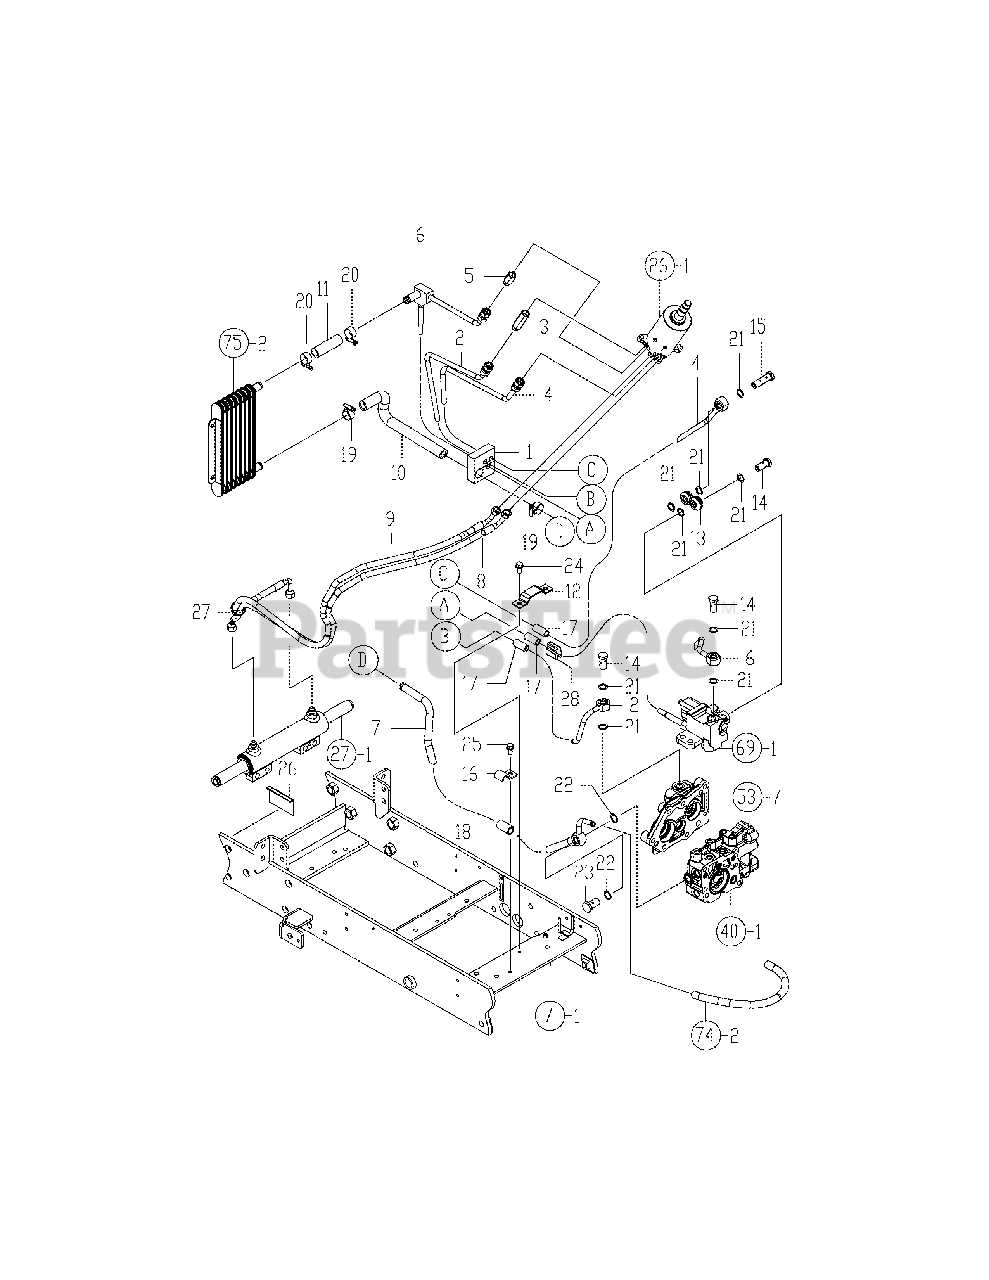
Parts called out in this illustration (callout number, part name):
2	Hp Pipe, Pump Cmp
3	Joint 9/16 Unf-70
4	Hp Pipe, Valve Cmp
5	Joint 9/16Unf-40
6	Lp Pipe, Cooler Cmp
7	Lp Pipe, Tank Cmp
8	Hp Hose L, Pst
10	Lp Hose A(Oil Cooler
11	Lp Hose B(Oil Cooler
13	Connector9/16Unf
14	Ball Joint Bolt 9/16
15	Ball Joint Bt L 9/16
19	Clamp, Hose 22
20	Clamp, Hose 22
21	Gasket, 14 X 1.0
22	Gasket, 16 X 1.0
23	Bolt, Joint 10
26	Seal,Wiring Harness
